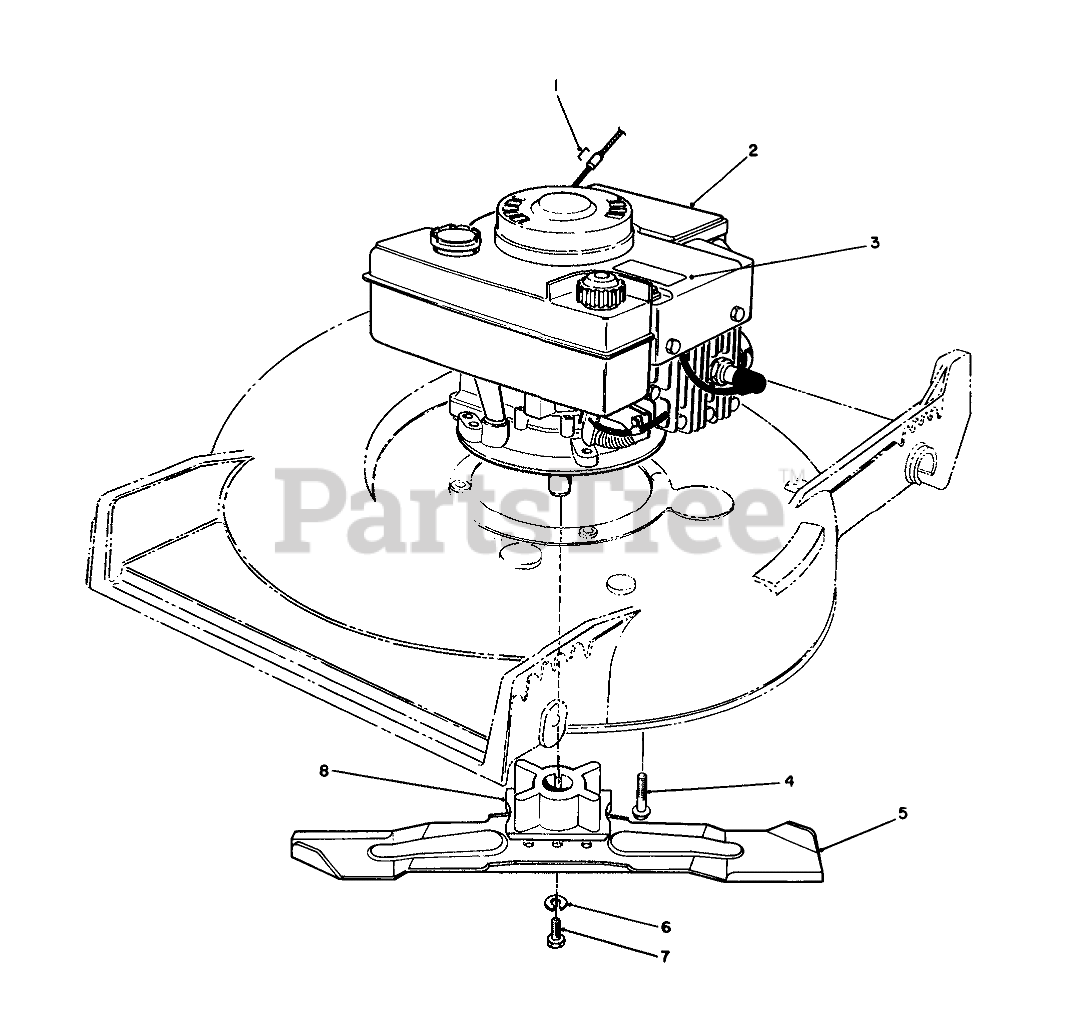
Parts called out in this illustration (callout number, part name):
1	Staple
3	Decal-Engine
4	3/8-16 X 2 CAPSCREW
5	BLADE-21in
6	WASHER-LOCK
7	SCREW-BLADE
8	BLADE RETAINER
